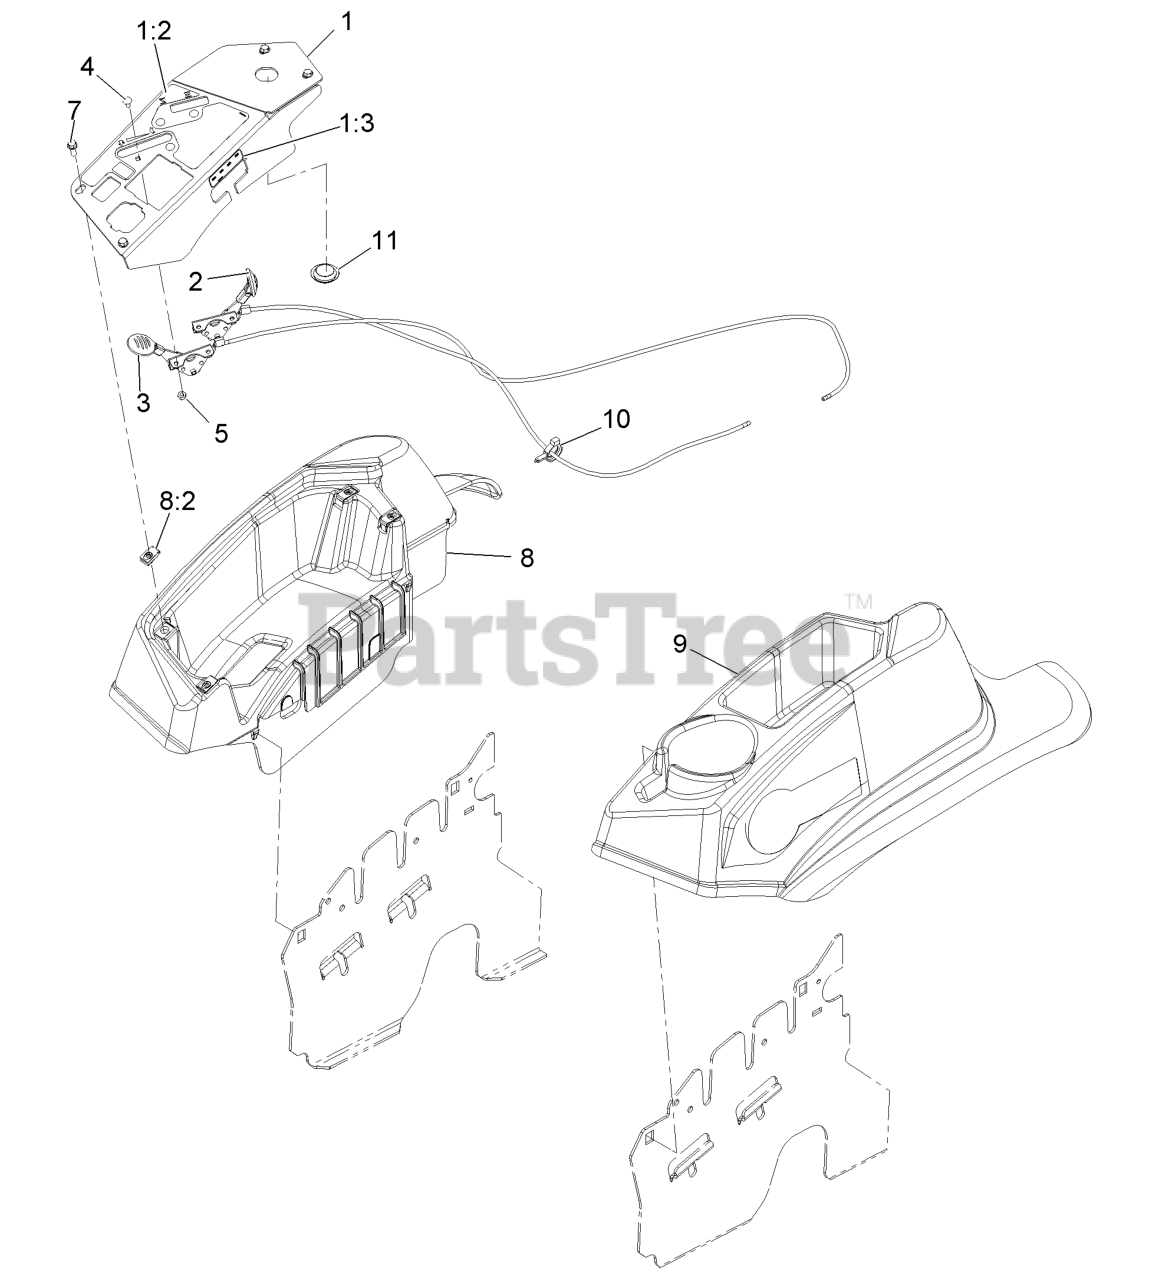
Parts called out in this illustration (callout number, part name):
1	ASM,CONSOLE PANEL W/DECAL
1:2	DECAL-CONTROL PANEL
1:3	DECAL-FUSE
2	ASM, CHOKE CABLE
3	ASM,THROTTLE CABLE
4	BOLT-CARR
5	NUT-LOCK, NI
7	SCREW-HWH
8	CONSOLE,RH AS ASM
8:2	Nut-Retainer-Panel 1/4-20
9	CONSOLE, LH AS
10	CLAMP-HOSE
11	PLUG-PLASTIC
